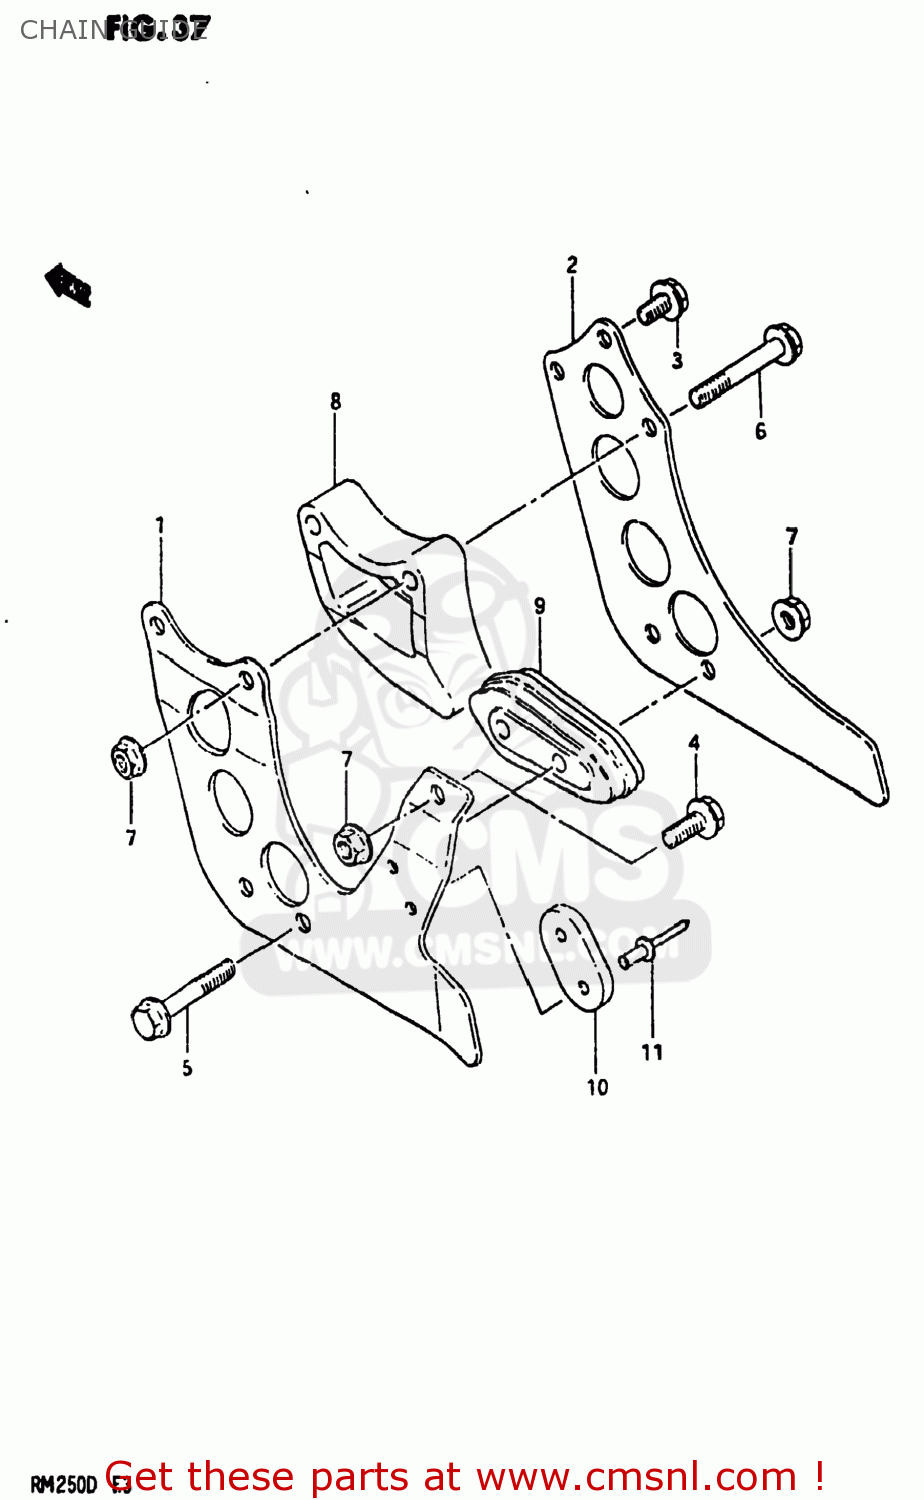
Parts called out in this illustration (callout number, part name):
1	PLATE,CHAIN GUIDE,OUTER
2	PLATE,GUIDE CHAIN
3	BOLT
4	BOLT
5	BOLT
6	BOLT,UNDER
7	NUT
8	DEFENSE,CHAIN GUIDE UPR
9	DEFENSE,CHAIN GUIDE
10	PAD,DRIVE CHAIN GUIDE
11	RIVET
